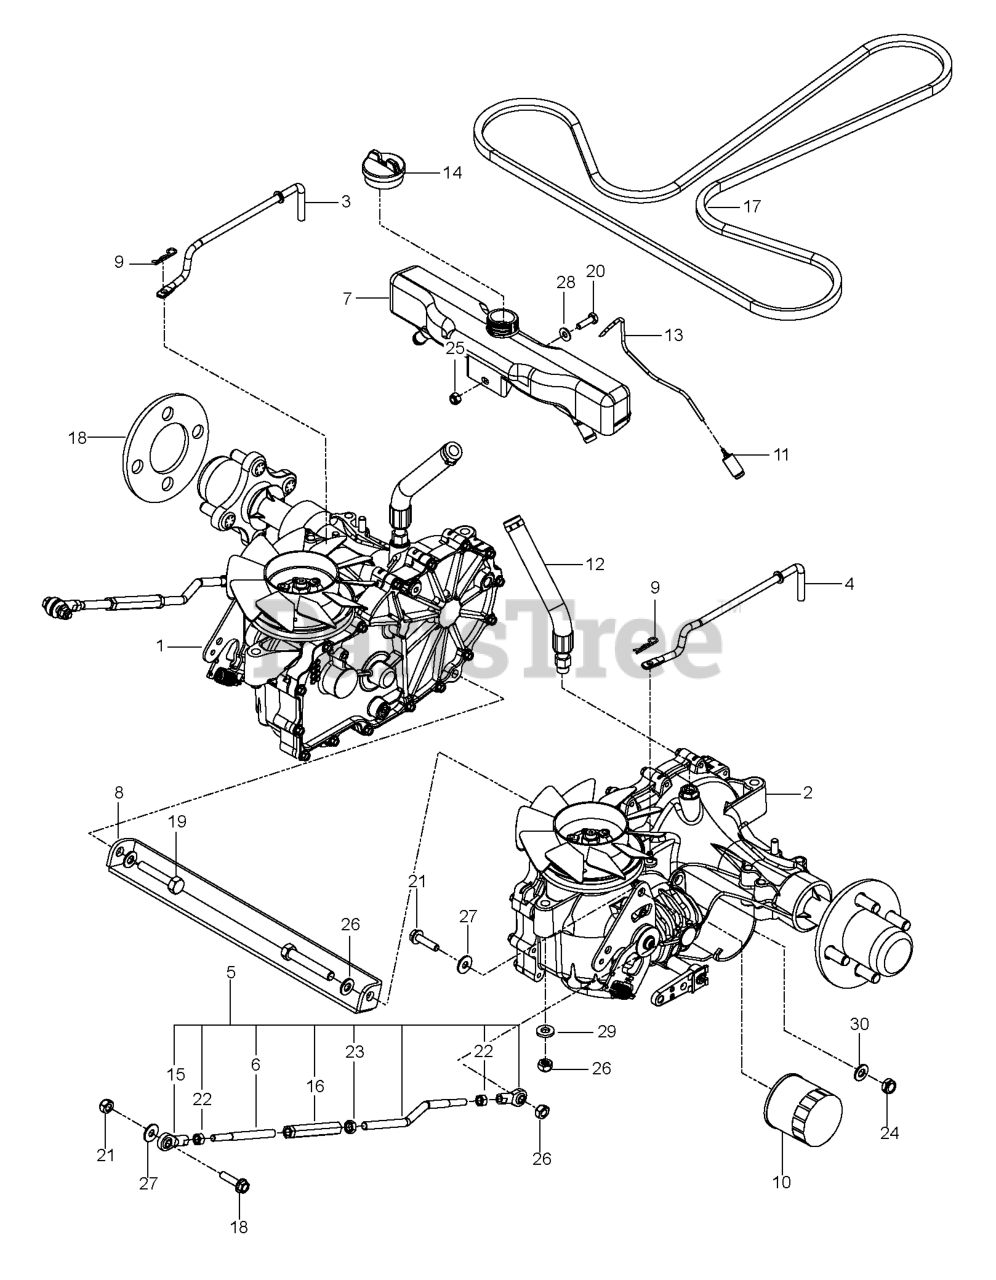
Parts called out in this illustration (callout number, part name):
1	HG_TRANS, ZT-3400, RT
2	HG_TRANS, ZT-3400, LT
3	LINKAGE, RIGHT BYPASS
4	LINKAGE, LEFT BYPASS
5	ASSEMBLY, CONTROL LINKAGE
6	LINKAGE, CONTROL, FT
7	TANK EXPANSION W/CAP
8	BRACKET CMBR XMSM BLK
9	HAIRPIN #2
10	HG_FILTER, ZT4800 52114
11	FUEL PICK-UP ASSY
12	HOSE ASSY, EXPANSION
14	CAP EXPANSION W/SEAL
15	BALL JOINT, RIGHT HANDED
16	TURNBUCKLE, 3/8
17	BELT, "AX", 86.7"
18	WHEEL SPACER ZT-3400 CARLISLE
19	HCS 3/8-16X2-1/4 LOC PATCH GR8
20	HCS 1/4-20X7/8 GR5
21	HHFS 5/16-18 X 1.25 TPBLT GD 5
23	NUT 3/8-24 JAM
24	LOCK NUT 3/8-15 GR C Z/Y
25	NUT.1/4-20.HEX.NYLOC.ZD
26	LOCK.NIUT,5/16-18.GRC.ZY
27	WASHER 5/16 FLAT
28	WASHER 1/4 SAE
29	WASHER.34X69X.10.GR8. ZY
30	WASHER 3/8 SAE FLAT
